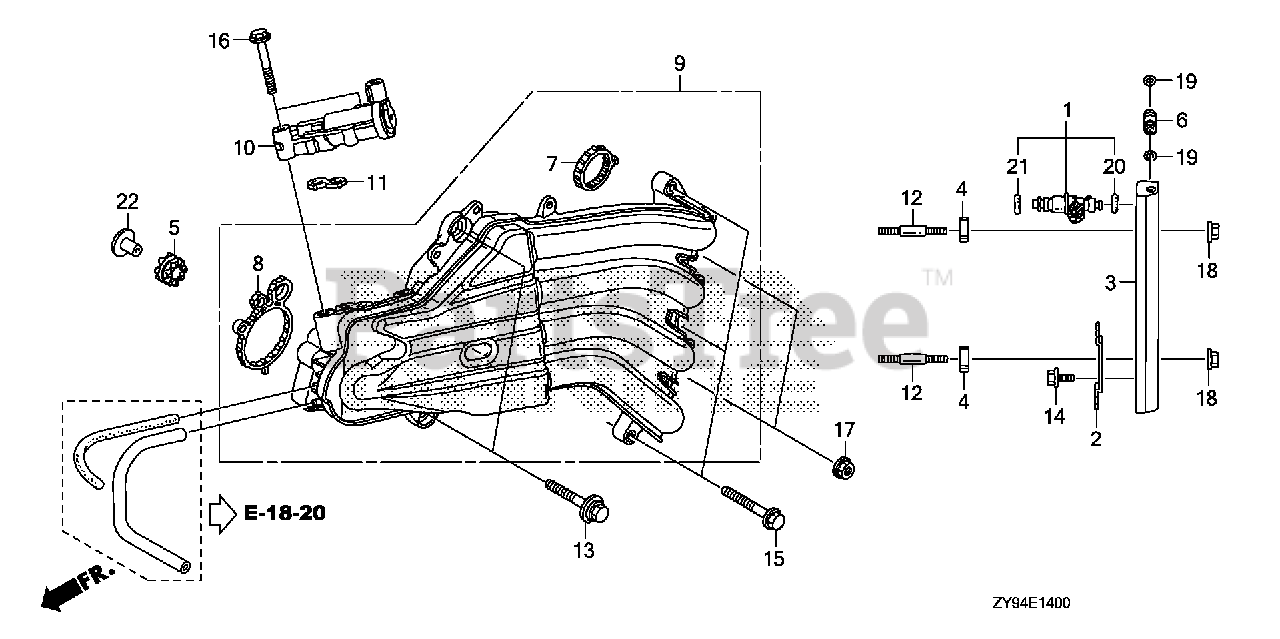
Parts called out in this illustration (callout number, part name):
1	INJECTOR ASSY., FUEL
2	CLIP, INJECTOR
3	LINE, FUEL
4	INSULATOR, FUEL PIPE
5	GROMMET, VAPOR SEPARATOR
6	JOINT, FUEL PIPE
7	GASKET, IN. MANIFOLD
8	GASKET, THROTTLE BODY
9	MANIFOLD, INLET
10	VALVE ASSY., ELECTRONIC AIR CONTROL
11	GASKET, ELECTRONIC AIR CONTROL VALVE
12	BOLT, STUD (6X40)
13	BOLT-WASHER (8X35)
15	BOLT, FLANGE (8X35)
16	BOLT, FLANGE (8X45)
17	NUT, FLANGE (8MM)
18	NUT, FLANGE (6MM)
19	O-RING (7.8X1.9) (ARAI)
20	O-RING (7.47X3.6)
21	O-RING (7.45X3.61) (NOK)
22	COLLAR (8.5X14.5)
